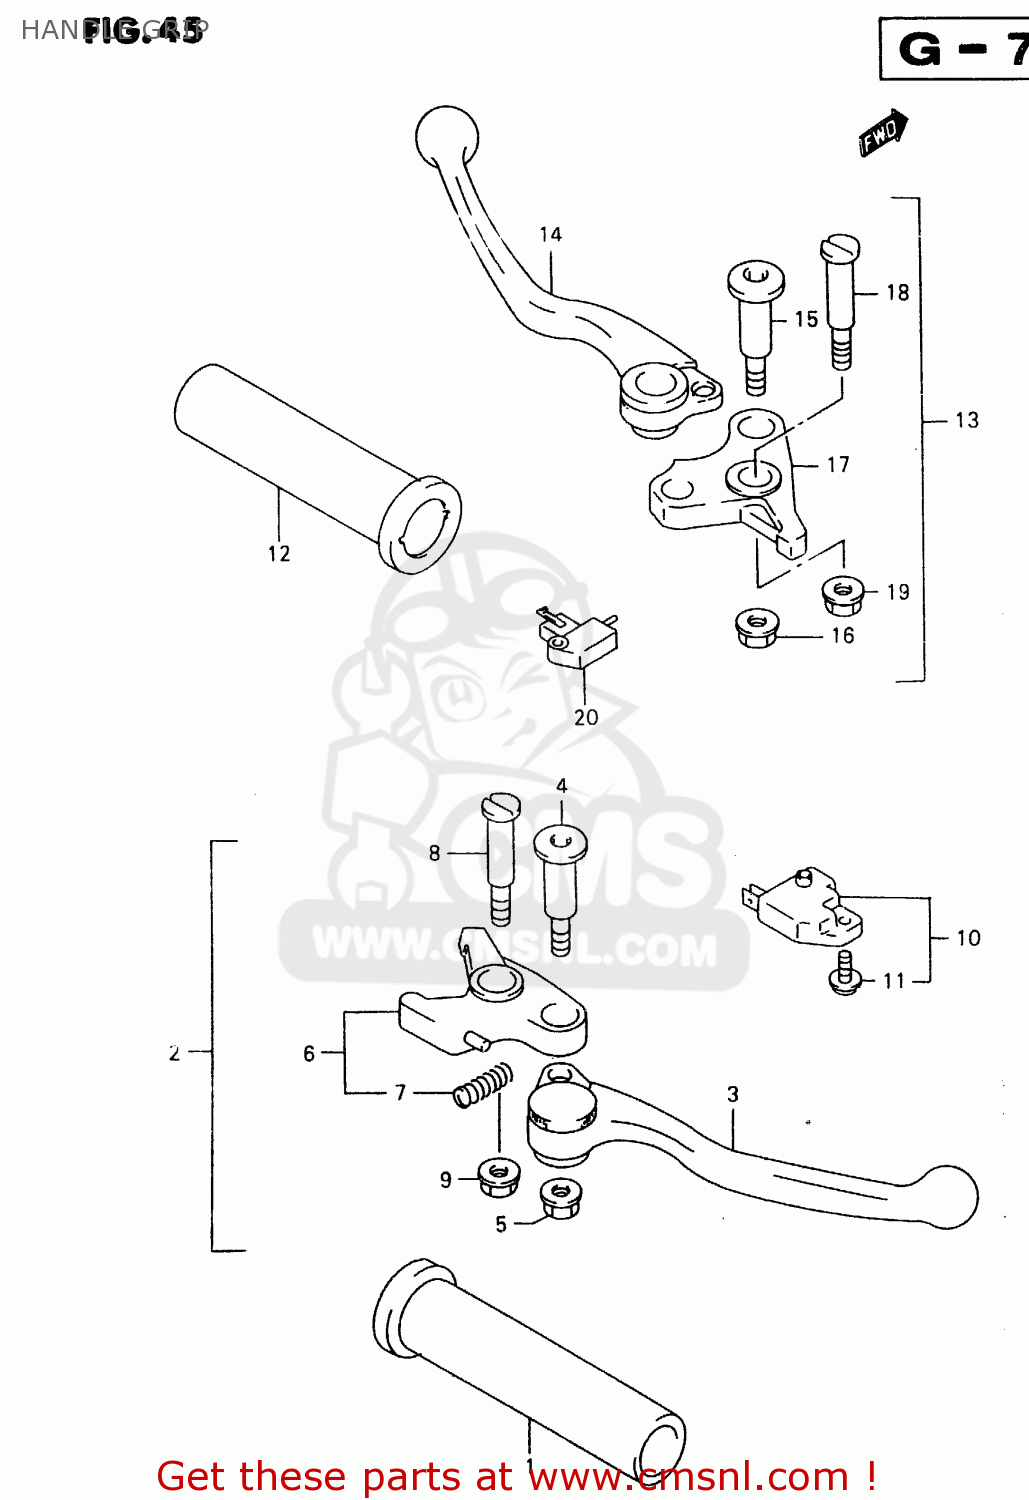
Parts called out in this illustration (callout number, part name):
1	GRIP,THROTTLE
2	LEVER ASSY,BRAKE
3	LEVER,ADJUST
4	BOLT,LEVER
5	NUT
6	RNOCKER
7	SPRING
8	BOLT,LEVER PIVOT
9	NUT,BRAKE LEVER
10	SWITCH ASSEMBLY,STOP
11	SCREW
12	GRIP,L
13	LEVER ASSY,CLUTCH
14	LEVER ASSY,CLUTCH
15	BOLT,LEVER
16	NUT
17	KNOCKER
18	BOLT,LEVER PIVOT
19	NUT,BRAKE LEVER
20	SWITCH ASSY,CLUTCH
